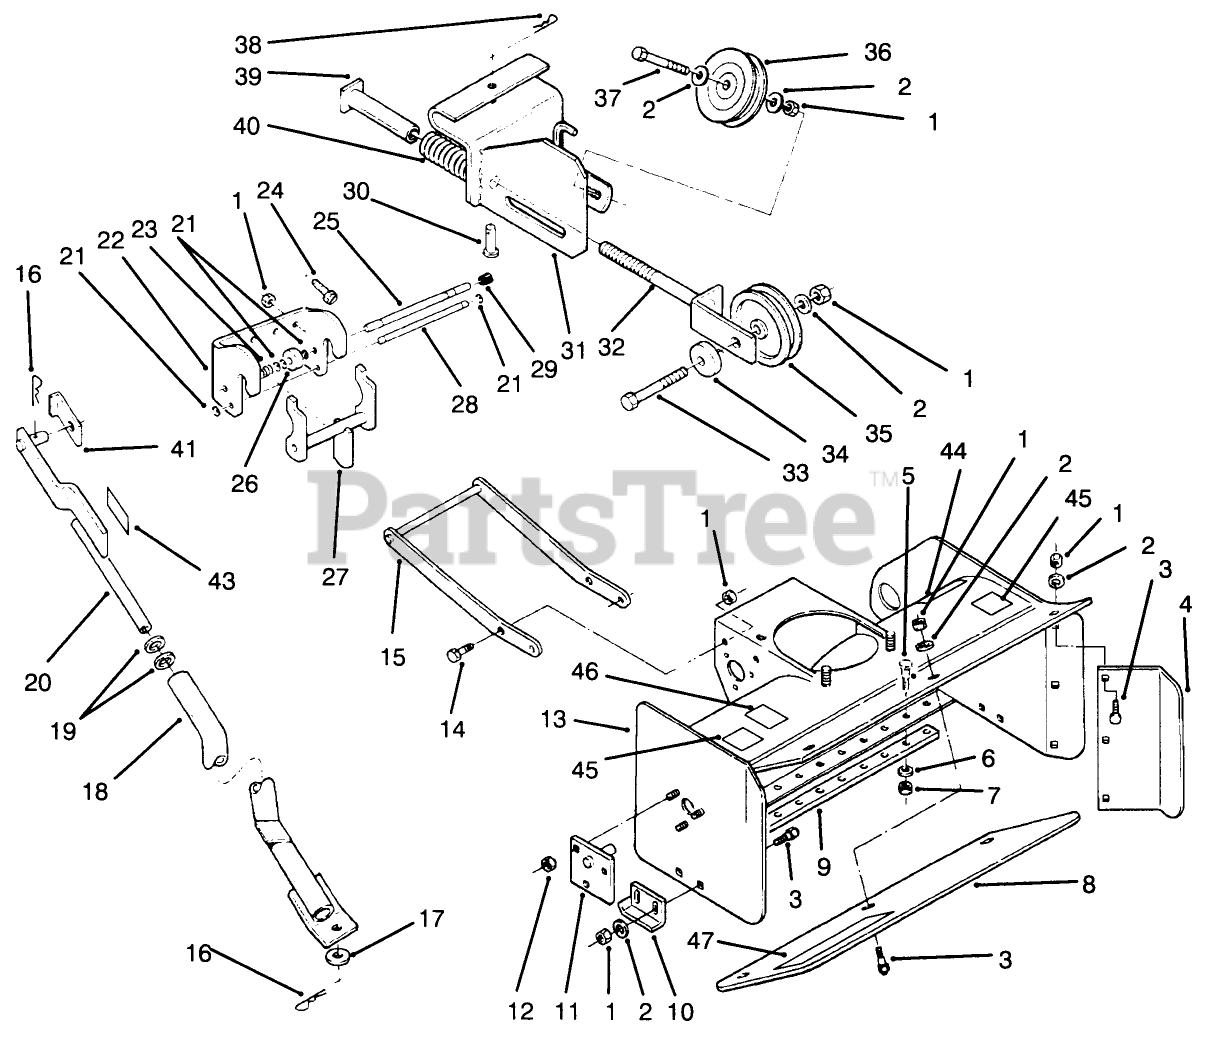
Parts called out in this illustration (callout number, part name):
1	NUT-LOCK, NI
2	WASHER-FLAT
3	BOLT-CARR
4	PLATE-EXTENSION, RH
5	SCREW-CARR
6	WASHER-FLAT
7	NUT-LOCK, NI
8	PLATE-EXTENSION
9	SCRAPER-REVERSIBLE
11	SUPPORT
12	NUT-LOCK, NI
13	Housing-Auger (Incl. Ref. #44-46)
14	SCREW-HH
15	Mounting-Frame
16	Hairpin
17	WASHER-FLAT
18	LIFT ROD
19	WASHER
20	Rod-Lift (Incl. Ref. #43)
21	RING-RETAINING
22	HITCH-FRONT
23	SPRING
24	SCREW-CARR
25	ROD-LOCK
27	LATCH
28	ROD-LATCH PIVOT
29	CAP-ROD, PLUNGER
30	CLEVIS PIN
31	BRACKET IDLER W.A.BLK
32	IDLER-SLIDE W.A.
33	SCREW-HH
34	BUSHING
35	PULLEY-IDLER, FLAT
36	PULLEY-IDLER
37	SCREW-HH
38	Hairpin Cotter
39	SPRING-TENSIONER
40	Spring-Compression
41	RETAINER CLIP
43	DECAL - WARNING
44	DECAL - WARNING
45	DECAL-DANGER
46	DECAL-WARNING
47	DECAL-ATTACHMENT
